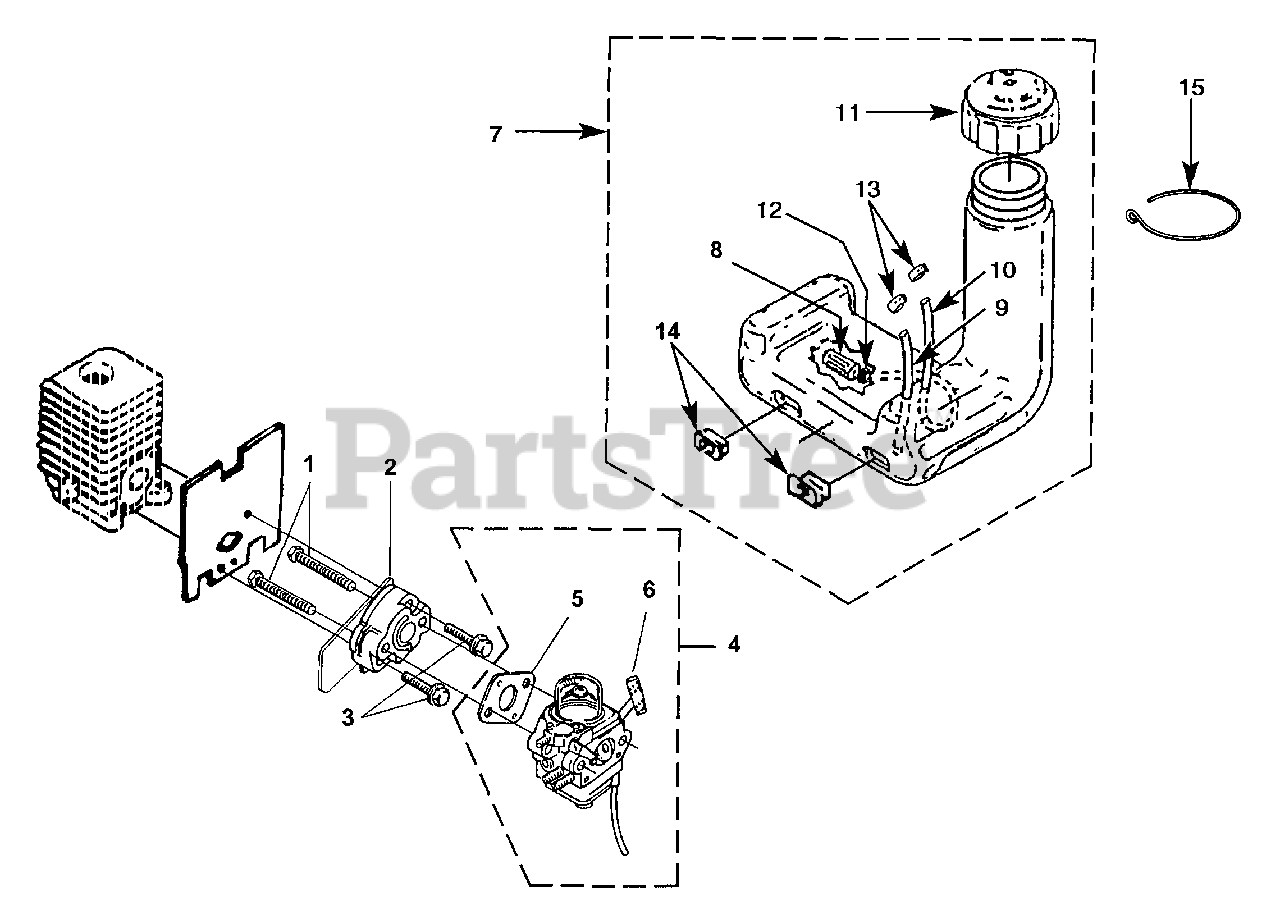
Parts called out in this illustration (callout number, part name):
1	SCREW-Machine (10-24 X 2 1/4")
2	HEAT DAM
3	SCREW-Sems (10-24 X 1.110")
4	CARBURETOR
5	GASKET-Carburetor
6	LEVER-Choke Rod (ZAMA)
7	FUEL TANK COMPLETE
8	FILTER-Fuel
9	TUBING-Rubber (5 1/2")
10	TUBING-Rubber (7")
11	FUEL CAP
12	CLAMP
14	BUMPER-Rubber
15	SUPPORT-Wire
